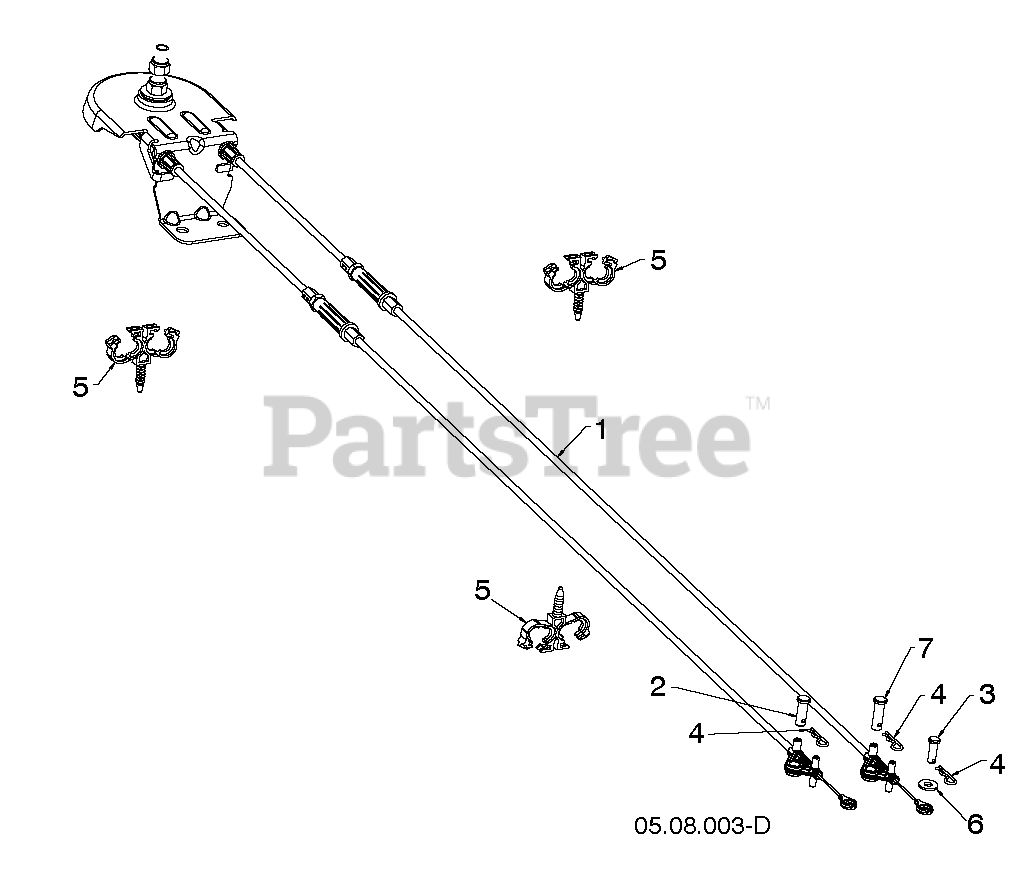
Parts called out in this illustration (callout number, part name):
1	Rotator Cable Assembly, Snow
2	Clevis Pin, 5/16 X .875
3	PIN.CLEVIS
4	Hair Pin, .059 X 1.125
5	Conduit Double Loop Clip
6	Flat Washer, .250 X .625 X .06
7	Clevis Pin, 5/16 X 1.0 L
